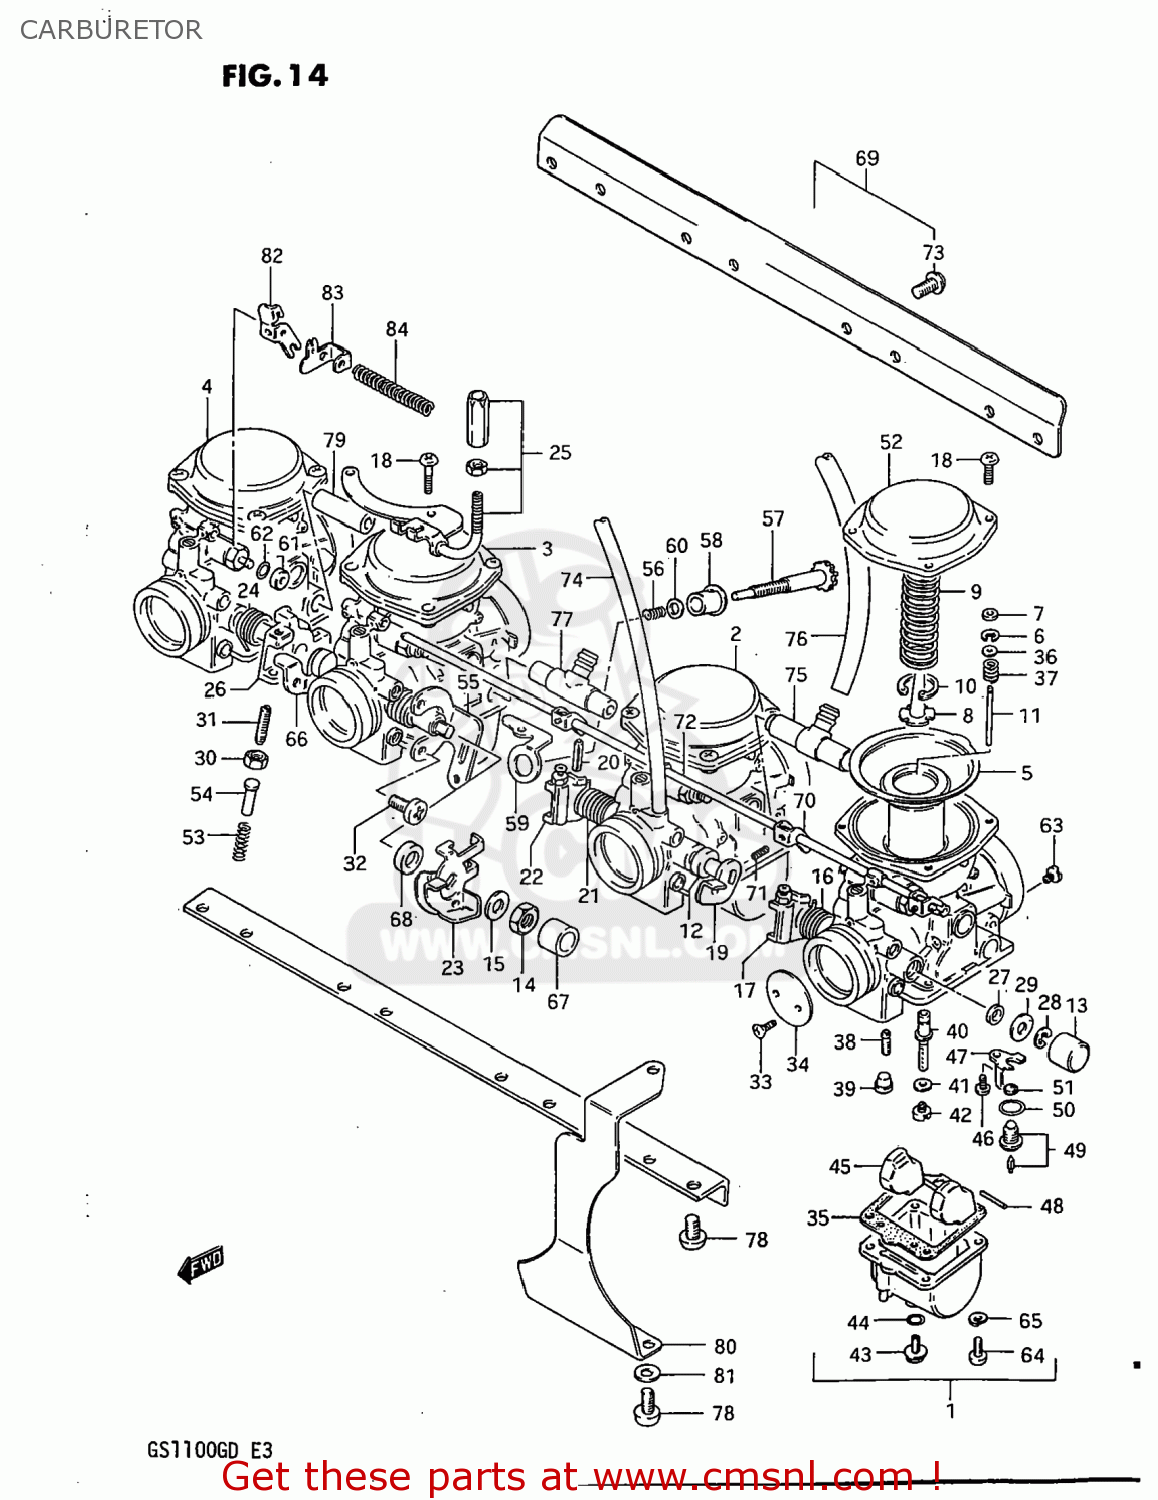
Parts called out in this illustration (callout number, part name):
1	CARBURETOR ASSEMBLY
2	CARBURETOR ASSEMBLY
3	CARBURETOR ASSEMBLY
4	CARBURETOR ASSEMBLY
5	DIAPHRAGM ASSEMBLY
6	CLIP,NEEDLE
7	RING
8	HOLDER,GUIDE
9	SPRING
10	E RING
11	NEEDLE,JET
12	GASKET
13	CAP
14	NUT 8MM
15	WASHER
16	SPRING,THROTTLE SHAFT
17	SHAFT,THROTTLE
18	SCREW
19	SHAFT,THROTTLE
20	PIN,THROTTLE SHAFT
21	SPRING,THROTTLE SHAFT
22	LEVER,THROTTLE SHAFT
23	LEVER ASSEMBLY,THROTTLE
24	SPRING,THROTTLE SHAFT
25	BRACKET,THROTTLE CABLE
26	SHAFT,THROTTLE
27	SEAL
28	E RING
29	GASKET,THROTTLE SHAFT (NAS)
30	NUT
31	SCREW
32	SCREW
33	SCREW
34	VALVE,THROTTLE
35	GASKET,FLOAT CHAMBER (NAS)
36	WASHER
37	SPRING
38	JET
39	PLUG,NEEDLE JET
40	JET,NEEDLE
41	WASHER,NEEDLE NOZZLE
42	JET,MAIN(115)
43	PLUG,DRAIN
44	GASKET (NAS)
45	FLOAT
46	SCREW 4X6
47	PLATE,NEEDLE VALVE FITING
48	PIN,FLOAT
49	VALVE ASSEMBLY,NEEDLE
50	O RING
51	FILTER
52	COVER,DIAPHRAGM
53	SPRING,THROTTLE SCREW
54	PIN,THROTTLE LEVER
55	BRACKET,THROTTLE ADJUST
56	SPRING
57	SCREW
58	BUSH
59	BRACKET,THROTTLE ADJUST
60	WASHER
61	CAP,STARTER VALVE
62	O RING
63	JET,AIR
64	SCREW
65	LOCK WASHER
66	SHAFT,THROTTLE
67	RING
68	RING
69	CARBURETOR ASSEMBLY
70	LEVER
71	SCREW
72	SHAFT,STARTER
73	SCREW
74	HOSE
75	NIPPLE
76	HOSE,CARBURETOR
77	NIPPLE
78	SCREW
79	NIPPLE
80	CLAMP
81	WASHER
82	PLATE,CHOKE CABLE
83	LEVER,CHOKE CABLE
84	SPRING,CHOKE CABLE
